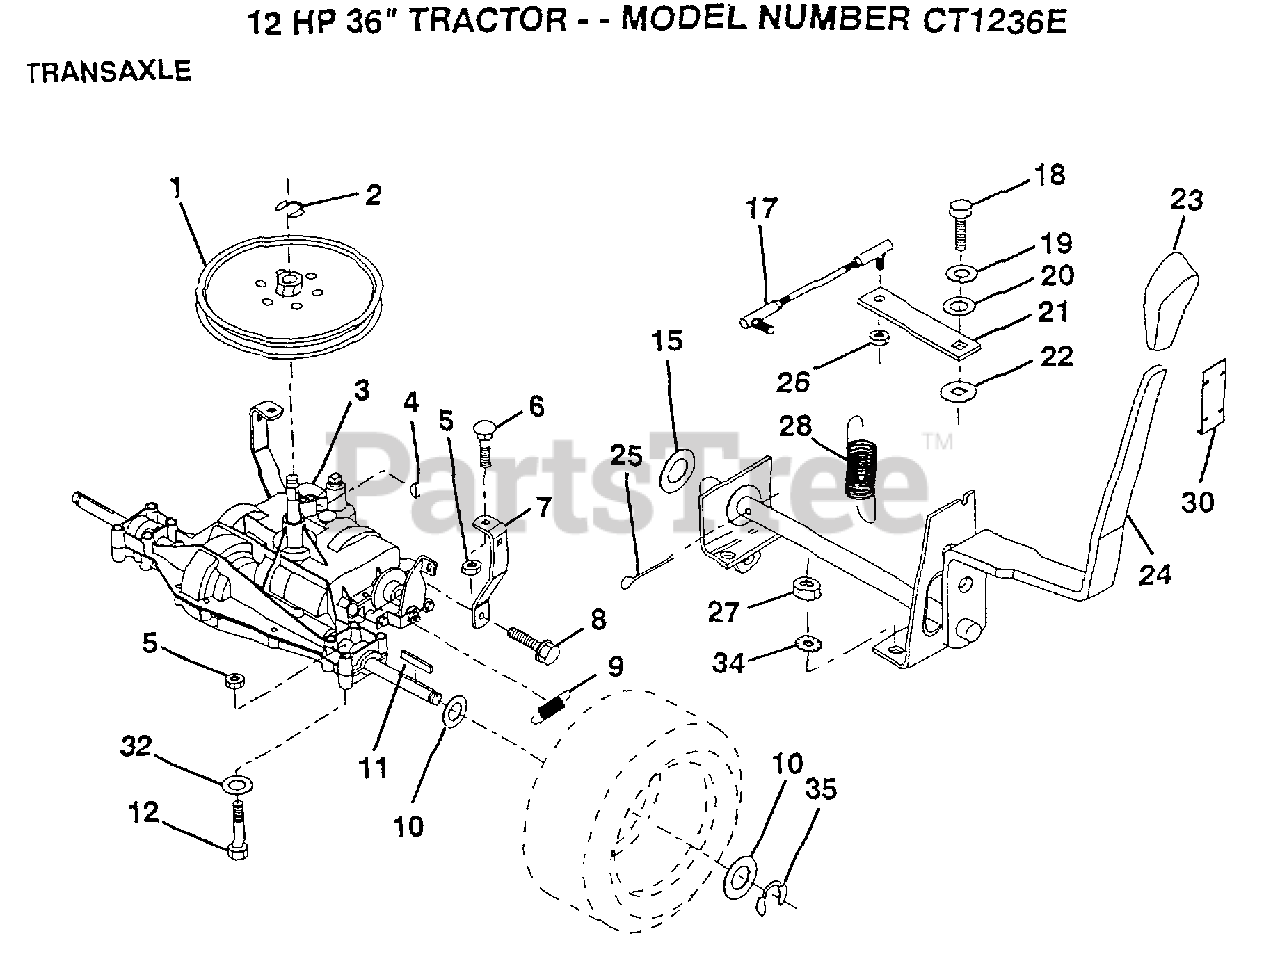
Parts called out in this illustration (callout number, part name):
1	PULLEY
4	KEY WOODRUFF #9
6	BOLT
7	"STRAP,TORQUE"
8	SCREW
10	WASHER
11	SQUARE KEY
12	BOLT
17	LINK SHIFT
19	LOCKWASHER
20	WASHER LT
22	WASH-SHFT PLT LT
23	"KNOB,SHT CONTROL"
25	PIN COTTER 1/8
26	NUT.LOCK.5/16-24
28	"SPRING,EXT"
30	KNOB RETAINER
32	WASHER
34	LOCKWASHER.5/16.E
35	E-RING LT
